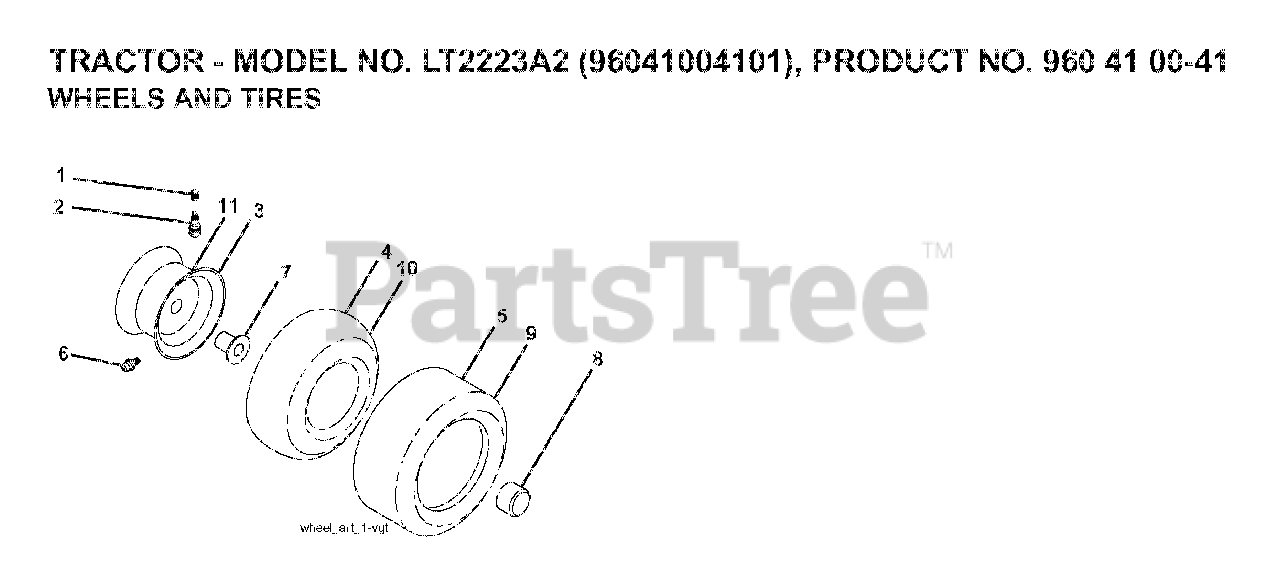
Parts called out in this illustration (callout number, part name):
1	VALVE CAP
2	VALVE STEM LT
3	RIM ASSEMBLY, FRONT
4	TUBE.5.3/4.5/6
5	TIRE HEAVY DUTY
6	FITTING LT
7	BEARING T
8	CAP, AXLE BLK
9	TIRE.R.TS.22 (22X9.50-12)
10	TUBE
11	RIM.ASM.12"REAR.SVC.417
